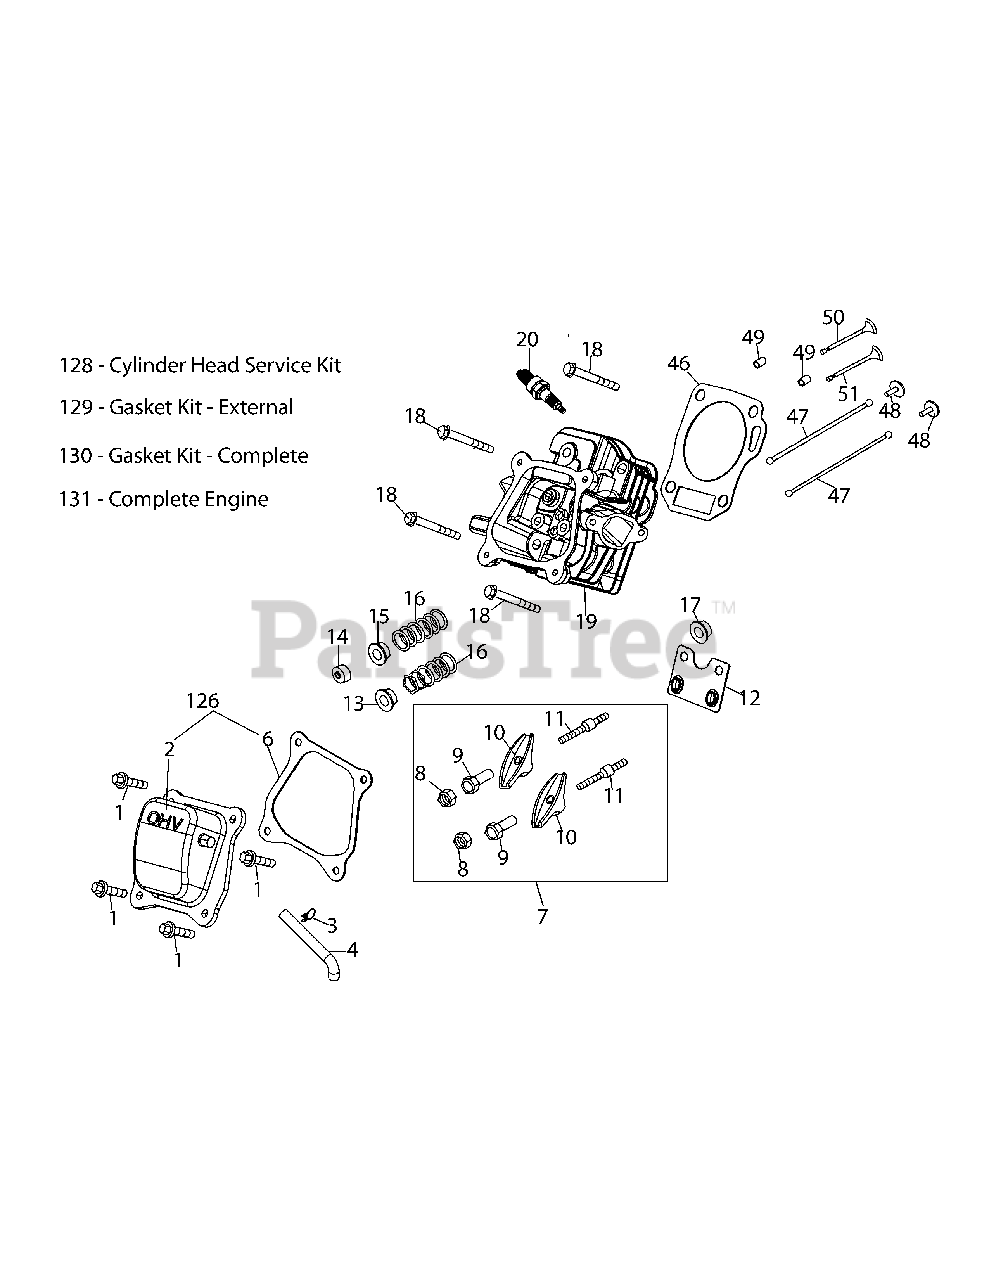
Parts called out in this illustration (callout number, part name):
1	Bolt M6×16
2	Valve Cover
3	Breather Hose Clamp
4	Exhaust Piping
6	Valve Cover Gasket
7	Rocker Arm Assembly
8	Nut, Pivot Locking
9	Adjusting Nut, Valve
10	Rocker Arm
11	Bolt, Pivot
12	Push Rod Guide
13	Retainer, Intake Valve Spring
14	Adjuster, Exhaust Valve
15	Retainer, Exhaust Valve Spring
16	Valve Spring
17	Intake Valve Seal
18	Bolt M8×55
19	Cylinder Head Assembly
20	Spark Plug/F6Rtc
46	Gasket, Cylinder Head
47	Push Rod Kit
49	Dowel Pin 10×16
126	Valve Cover Kit
128	Cylinder Head Service Kit
129	Gasket Kit - External
130	Gasket Kit - Complete
131	Complete Engine
